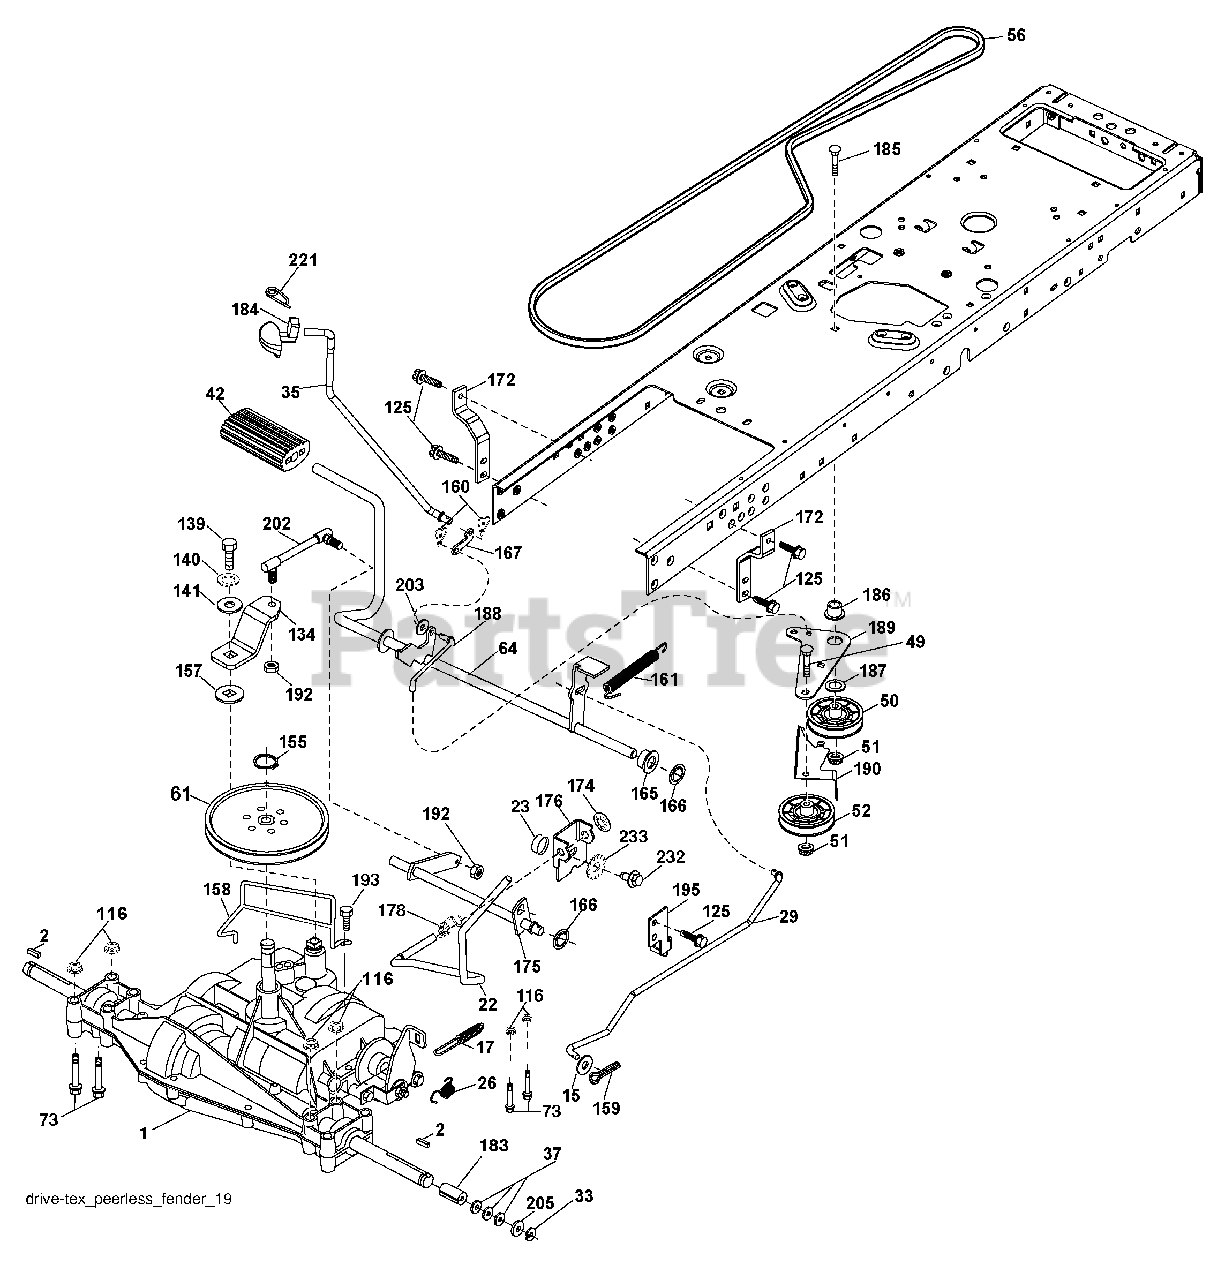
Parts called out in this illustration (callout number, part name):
2	Key Square
15	Washer 13/32 x 13/16 x 16 Ga.
17	Spring, Brake
26	Spring Brake Return
29	Rod, Brake
35	Rod, Brake, Park
37	Washer 25/32 x 1-1/4 x 16 Ga.
42	Cover, Foot Pedal
50	Pulley Idler Flat
51	Lock Nut 3/8-16
52	Idler V-Groove
56	V-Belt, Drive
61	Pulley Transaxle
64	Shaft Asm. Pedal Brake Control
70	Console
73	Bolt 5/16-18 Gr. 5
74	Screw 1/4 x 1/2
116	Nut Lock Hex Flange 5/16-18
125	Screw 5/16-18 x 3/4
139	Bolt 1/4-28 unf Gr. 8 w/Patch
140	Washer Lock Hvy Helical 1/4
141	Washer 9/32 x 3/4 x 10 Ga.
155	Ring Retainer
157	Washer Plate Shift
158	Belt Keeper
159	Pin Cotter 1/8 x 3/4
160	Retainer Clip
161	Spring, Return, Clutch
165	Busing Shaft Brake Hand Control
166	Nut Push .625
167	Latch Brake Parking
172	Strap Torque LH
175	Shaft Asm. Shift
176	Arm Clevis Rod Shift
178	Spring Shift
183	Spacer Axle
184	Handle Parking
186	Spacer Retainer
187	Washer
188	Link Clutch Ground Drive
189	Bellcrank Ground Drive
190	Keeper Bellcrank Ground Drive
192	Nut Lock Center 1/4-28 Fnthd
193	Screw 5/16-18 x 3/4
195	Bracket Brake Rod
202	Link Transaxle
203	Washer 11/32 x 11/16 x 16 Ga.
205	Washer 25/32 x 1-5/8 16 Ga.
221	Retainer Spring Clip Handle
232	Bolt Fin Hex 7/16-14 x 1 Gr. 5
233	Washer Serrated
